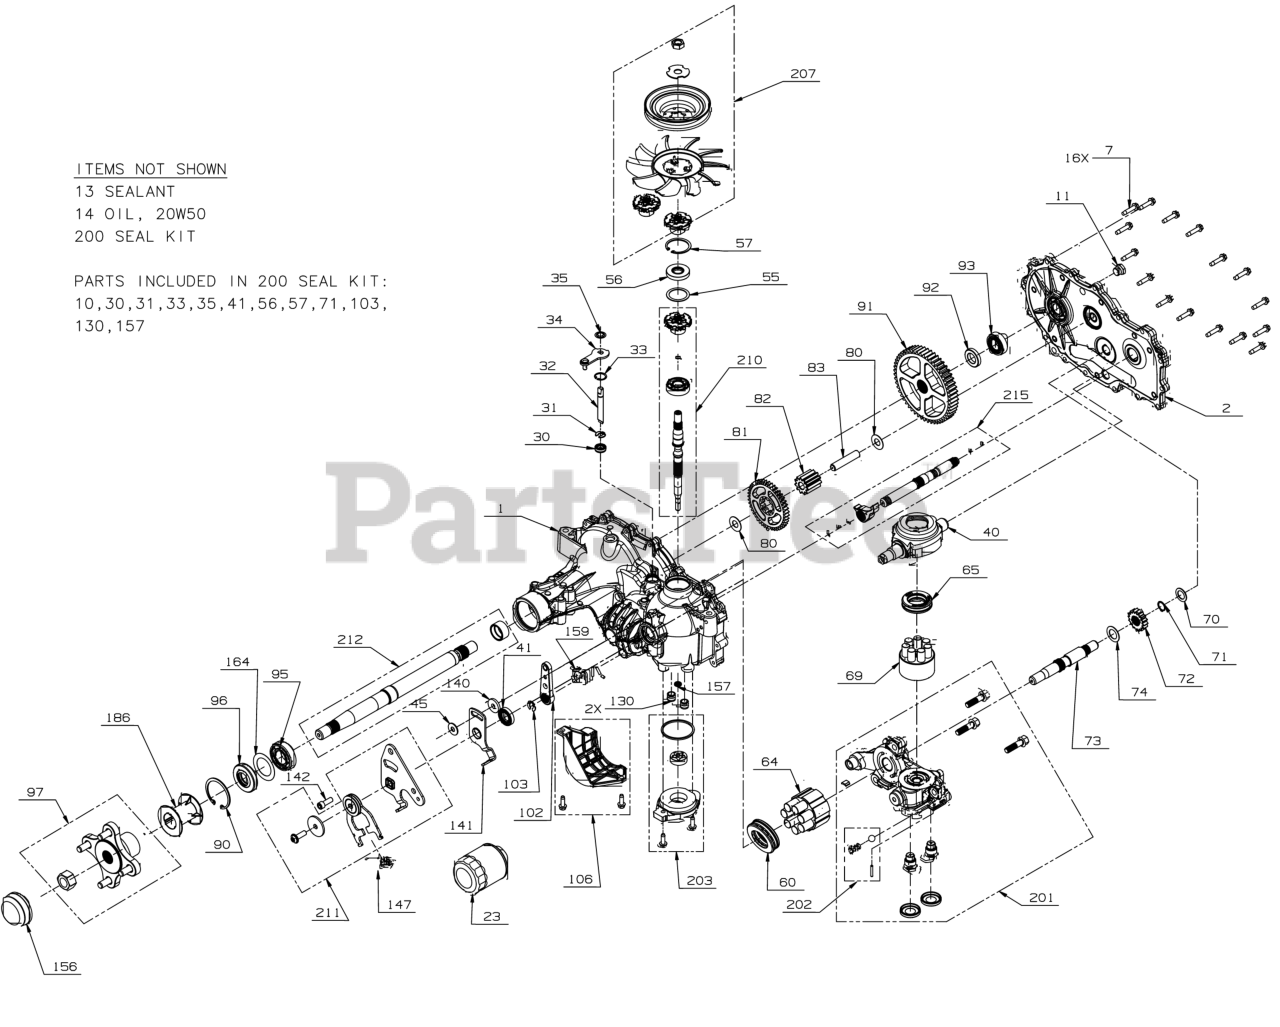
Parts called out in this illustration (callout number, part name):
1	HUOSING KIT-MAIN R
2	COVER KIT-SIDE (RH)
7	SCREW-WASHER HEAD
11	VENT PLUG
13	SEALANT-HOUSING
23	OIL FILTER
30	SEAL-LIP .375 X .75 X .25
31	RETAINING RING
32	BYPASS RODS
33	RETAINING RING
34	ARM-BYPASS
35	RETAINING RING
40	SWASHPLATE-TRUNNION
45	FLAT WASHER
55	WASHER 1.23X1.56X
57	RETAINING RING
60	THRUST BEARING
64	CYLINDER BLOCK ASSEMBLY
65	THRUST BEARING
69	BLOCK KIT-7 PISTON
70	FLAT WASHER
71	RETAINING RING
72	GEAR-16T (STEEL)
73	MOTOR SHAFT
74	MOTOR SHAFT WASHER
81	GEAR-43 T
82	GEAR-11 T
83	PIN-JACKSHAFT
90	RETAINING RING
91	GEAR-54 T
92	SPACER .75X1.32X.257
93	BALL BEARING
95	BALL BEARING
97	HUB-4 BOLT WHEEL
102	BRAKE LEVER
103	RETAINING RING
106	FILTER GUARD KIT
130	TUBE-CHARGE TRIPLE O-RING
140	SPACER .32 x 1.005 x .179
141	ARM-NEUTRAL (RH)
142	SCREWS KIT-RTN
147	EXTENSION SPRING
156	COVER-NUT
157	KIT-GEROTOR SEAL
159	TORSION SPRING CCW
186	TUBE-AXLE 2.03
200	SEAL KIT
201	CENTER SECTION KIT (RH)
202	KIT-CHARGE RELIEF
203	CHARGE KIT
207	FAN & PULLEY KIT
209	PULLER KIT-HUB
210	INPUT SHAFT KIT
211	RETURN KIT-NEUTRAL (RH) ZT2800 RZT
212	SHAFT KIT-AXLE
215	OUTPUT SHAFT KIT (RH)
